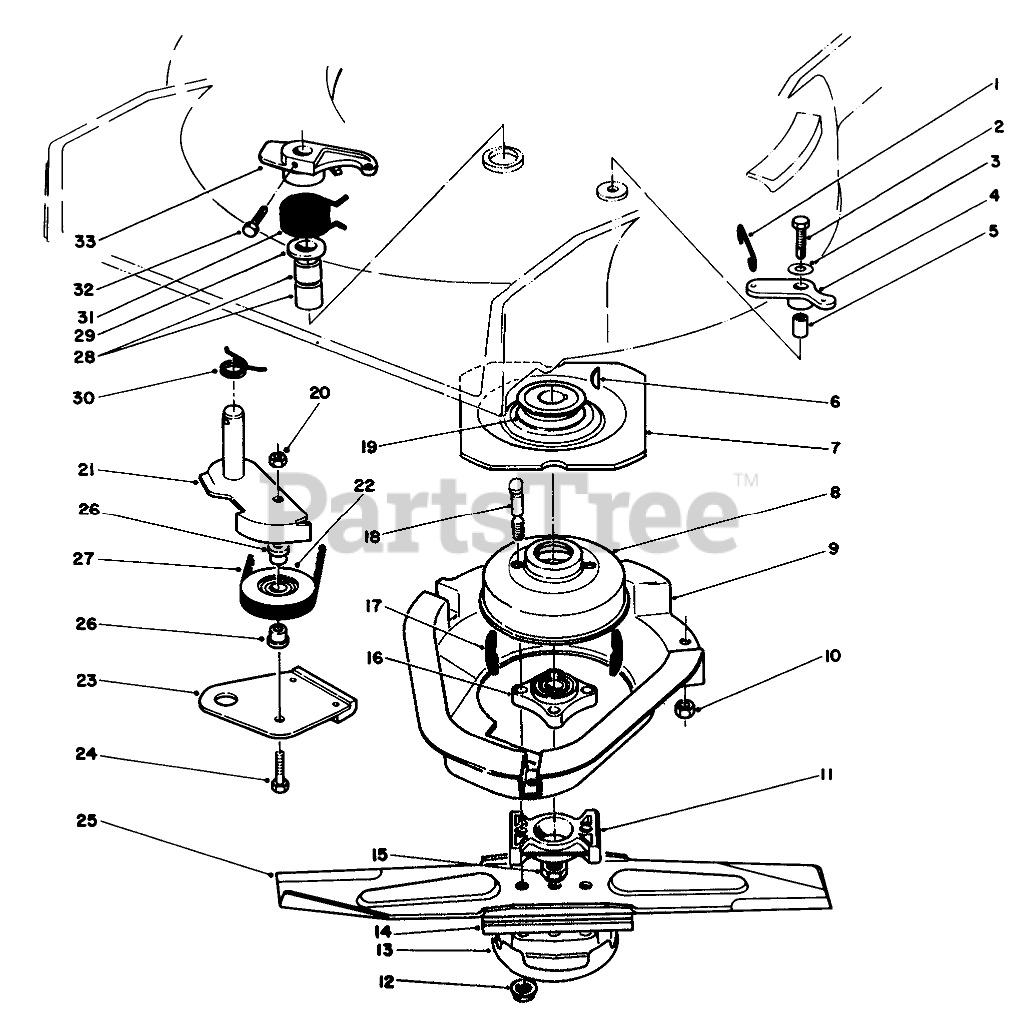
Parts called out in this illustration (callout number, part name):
1	LINK-CONTROL
2	Capscrew
3	WASHER-PLAIN
4	BELLCRANK
5	SLEEVE-BELLCRANK
6	KEY-WOODRUFF
7	Flywheel
8	Drum-Brake
9	Shield
10	NUT-LOCK, NI
11	SPACER-BLADE
12	NUT-LOCK
13	CUP-SCALP, ANTI
14	Stiffener
15	NUT-LOCK, NI
16	HUB ASM
17	DAMPENER-VIBRATION
18	BOLT-BLADE
19	PULLEY
20	NUT-LOCK, NI
21	ARM-IDLER
22	PULLEY-IDLER
23	BRAKE PLATE ASM
24	SCREW-HH
25	Blade-21" (Incl. Ref. #14)
26	SPACER-PULLEY, IDLER
27	V-BELT
28	BEARING
29	WASHER
30	SPRING-TORSION
31	SPRING-TORSION
32	SCREW-HH
33	LEVER
